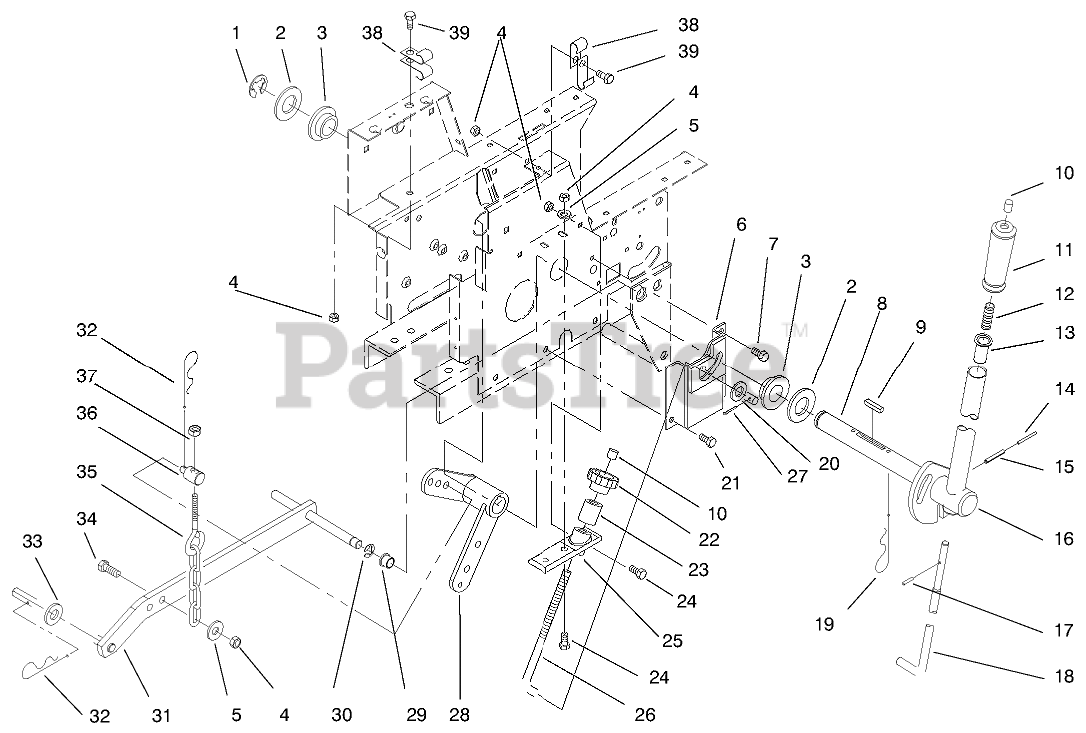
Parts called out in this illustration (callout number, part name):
1	RING-RETAINING
2	WASHER-FLAT
3	BEARING-FLANGE
4	NUT-LOCK, NI
5	WASHER-PLAIN
6	LIFT LEVER ASM
7	Bolt
8	SHAFT-LIFT LEVER
9	KEY-SQUARE
10	CAP-ROD, PLUNGER
11	GRIP-HANDLE
12	SPRING-COMPRESSION
13	RETAINER-SPRING
14	PIN-SPRING
15	PIN-ROLL
16	LIFT HANDLE ASM
17	PIN-SPIROL
18	ROD-LATCH LIFT
19	PIN-HAIR
20	WASHER-FLAT
21	SCREW-SELF TAP
22	KNOB-LIFT CONTROL
23	SLEV-LIFT ADJS
24	SCREW-HH
25	CASTING-LIFT LEVER
26	ROD-HEIGHT CONTROL
27	PIN-COTTER
28	LIFT LEVER ASM
29	BUSHING
30	RING-RETAINING, EXTERNAL
31	LIFT BAR ASM
32	PIN-HAIR
33	WASHER-FLAT
34	SCREW-HH
35	CHAIN-LIFT
36	TRUNNION-LIFT
37	NUT-LOCK, NI
38	CLIP
39	SCREW-HH
